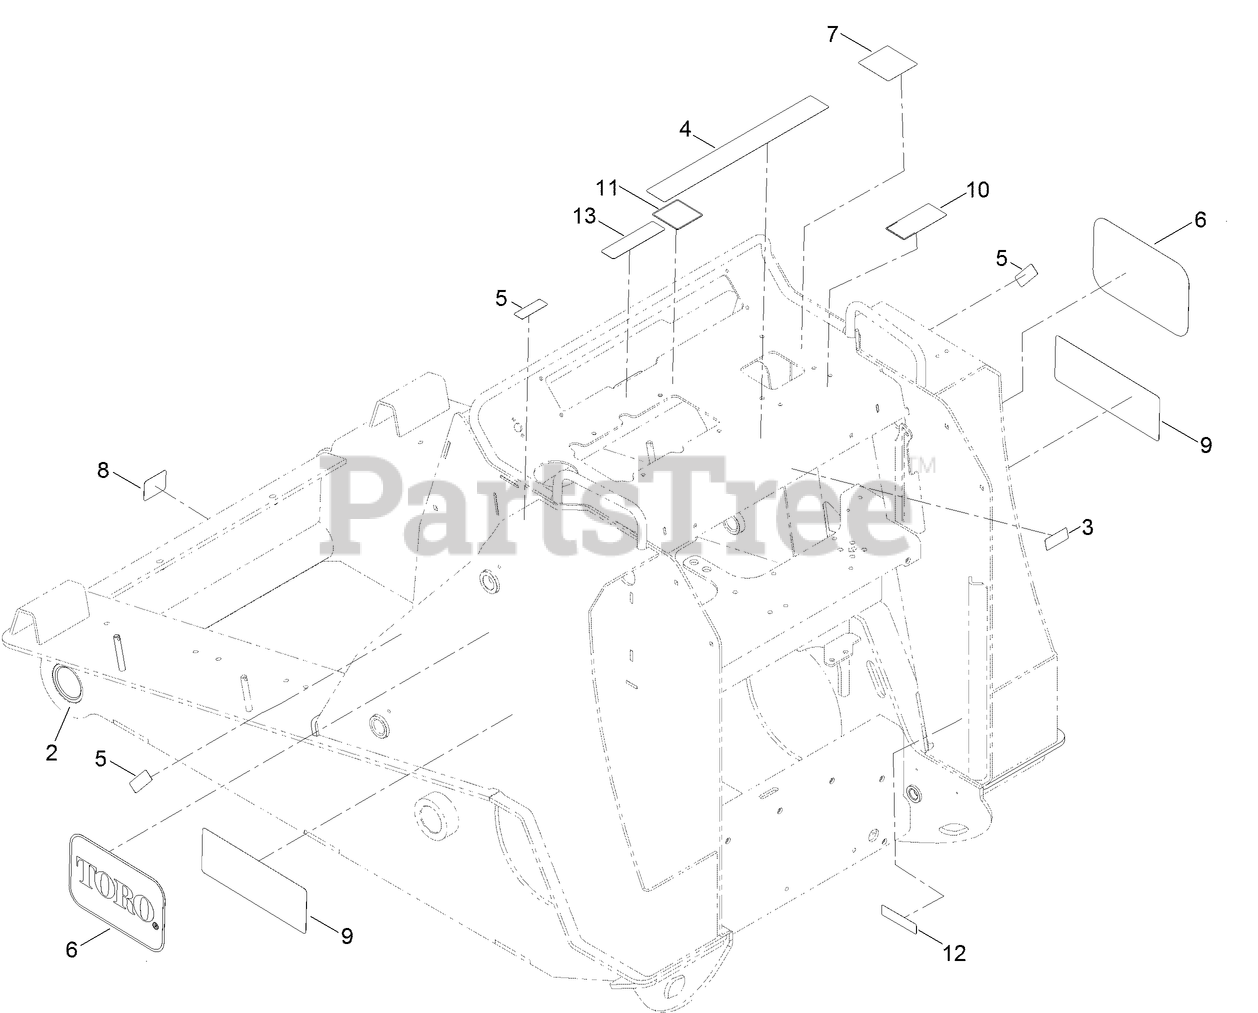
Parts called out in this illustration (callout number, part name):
2	BUSHING-CYL
3	DECAL-SURFACE, HOT
4	DECAL-SAFETY
5	DECAL-WARNING, PINCH POINT
6	DECAL
7	DECAL-CONTROL, LOADER
8	DECAL-TIE DOWN
10	DECAL-EXTENDED ARM SAFETY
11	DECAL-LOADER CONTROLS
12	DECAL-ARRESTOR, SPARK
13	DECAL-ARM,RAISED
